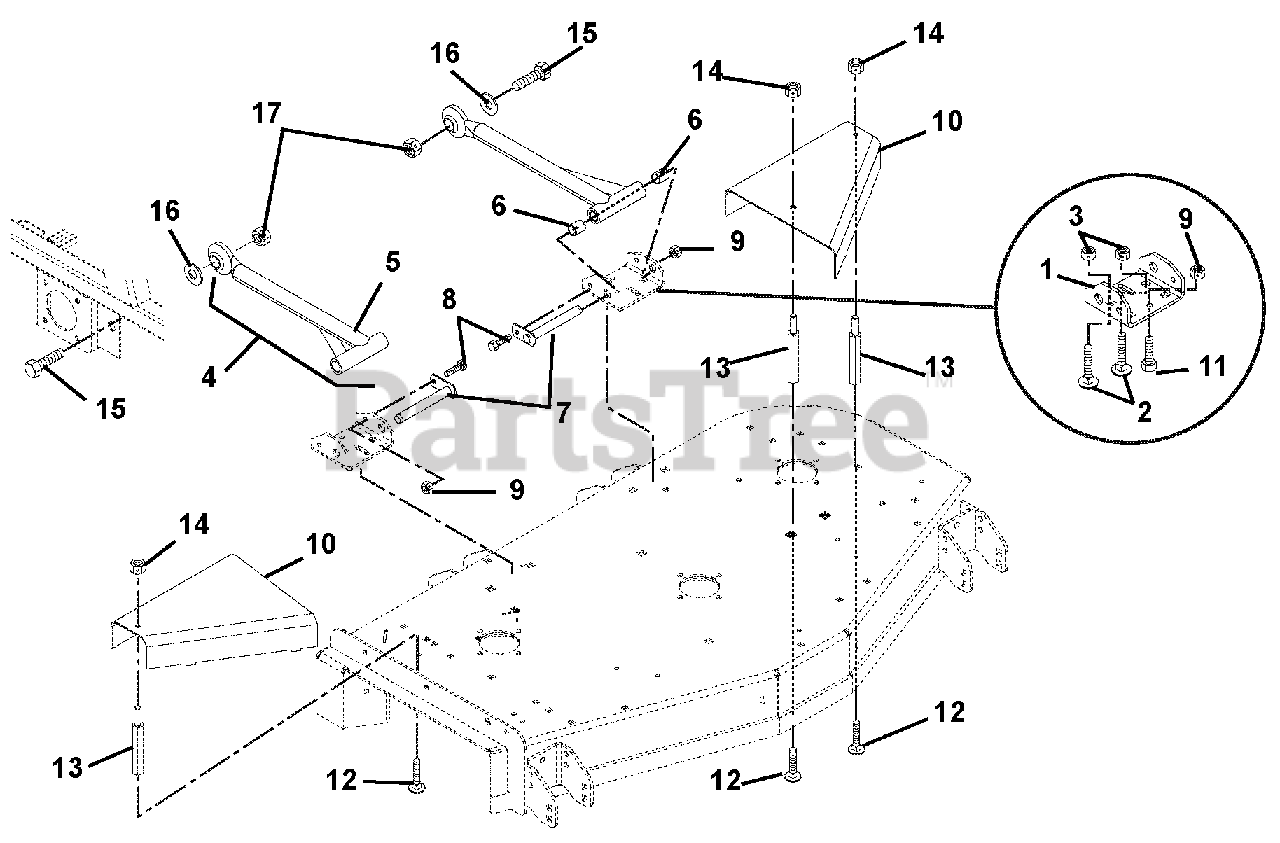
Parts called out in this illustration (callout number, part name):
1	Bracket, Mower Mounting (Rear)
2	Bolt, Round Head Square Neck .50-13 x .75 Grade 5
3	Nut, Locking Center Jam .50-13
4	Assembly, Mower Mounting Arm (Includes Items 5 and 6)
5	Weldment, Mower Mounting Arm
6	Bearing .75 x .875 x 1.00
7	Weldment, Mower Mounting Pin
8	Bolt, Hex .38-16 x 1.00 Grade 5
9	Nut, Locking Top Flange .38-16
10	Guard, Pulley Left Hand
11	Bolt, Round Head Square Neck .38-16 x .75 Grade 5
12	Bolt, Round Head Square Neck .31-18 x .75
13	Standoff 2.75 x 5/16-18
14	Nut, Locking Top Flange .31-18
15	Bolt, Hex .875-9 x 2.75 Grade 5
16	Washer, Flat Steel .875 x 1.50 x .120
17	Nut, Locking Center .875-9
